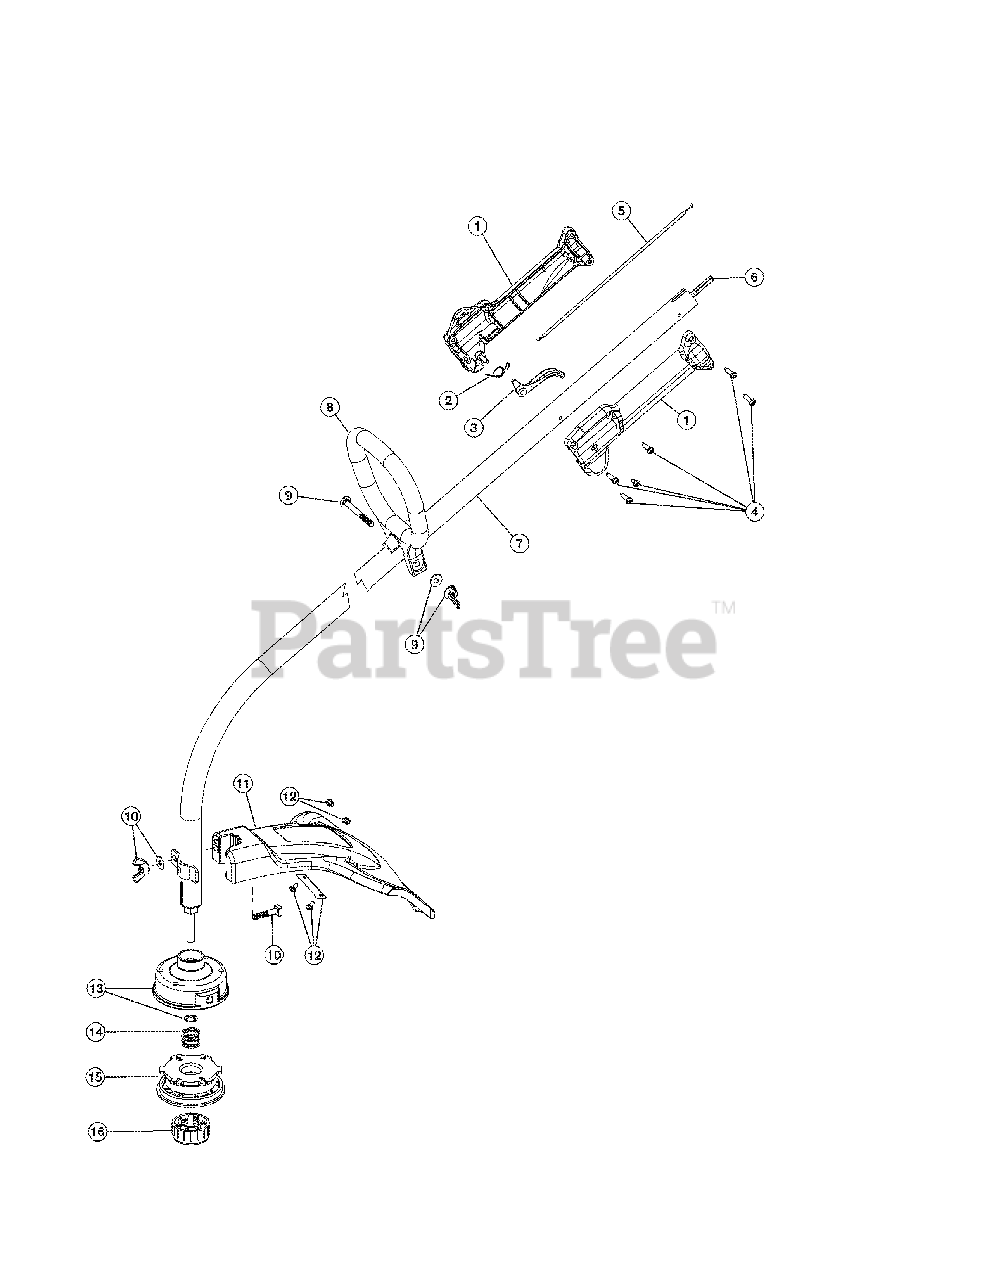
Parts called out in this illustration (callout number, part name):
1	Throttle Housing Assembly (includes 2-4)
2	Throttle Trigger Spring
3	Throttle Trigger
4	Throttle Housing Screws
5	Throttle Cable
6	Flexible Drive Shaft
7	Drive Shaft Housing
8	D-Handle Assembly (includes 9)
9	D-Handle Hardware
10	Guard Mounting Hardware
12	Blade Assembly
13	Outer Reel w/Retainer
15	Inner Reel
16	Bump Knob
